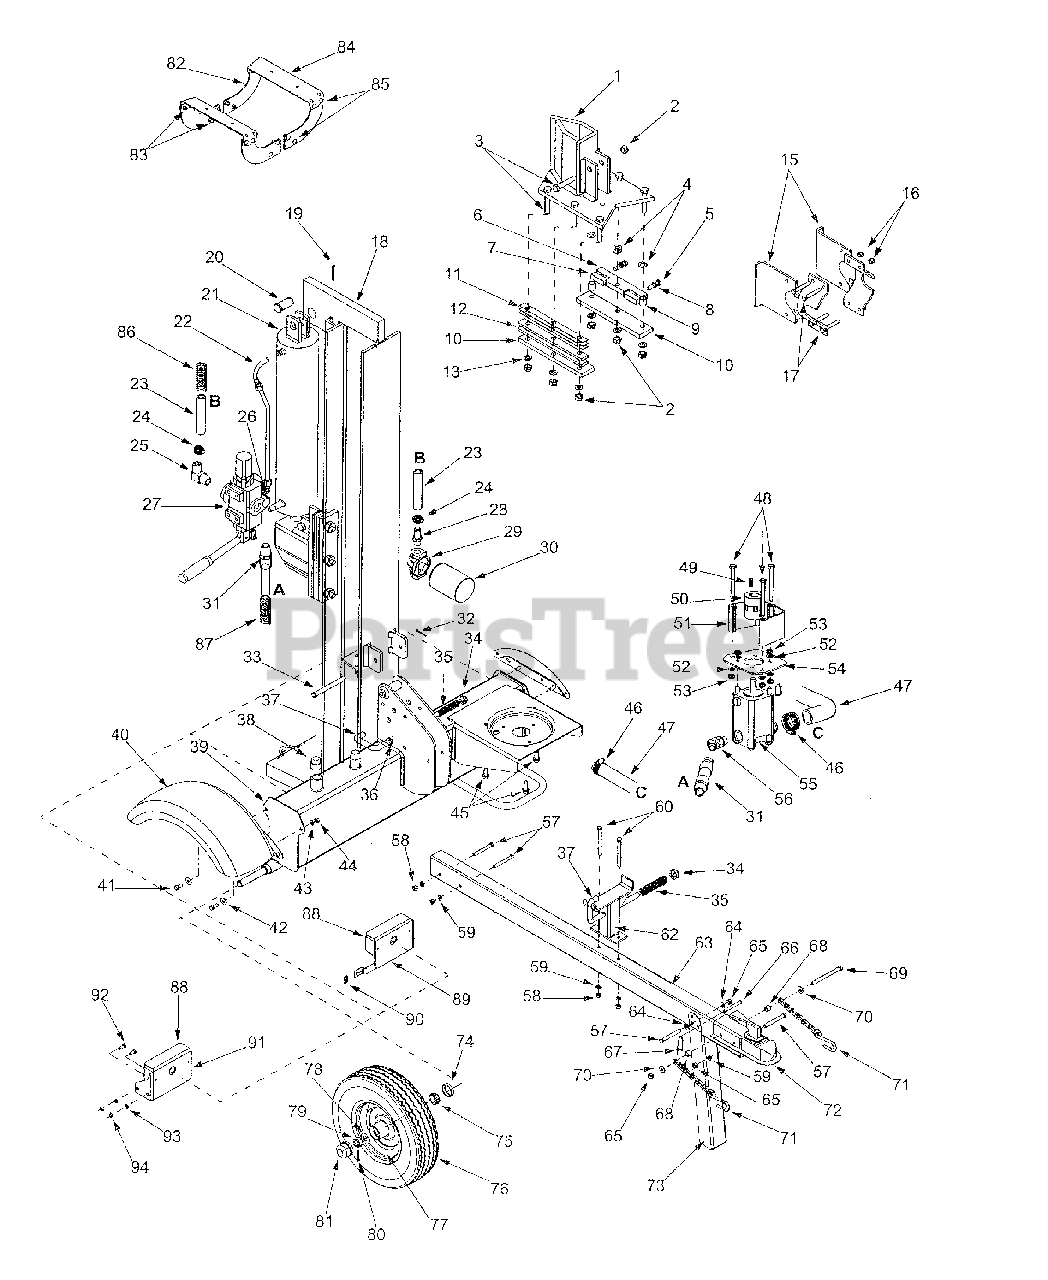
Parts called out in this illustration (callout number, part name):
2	Lock Nut 1/2-20
3	Hex Cap Screw 1/2-20 x 2.75
4	Flat Washer .531 ID x .93 OD
5	Hex Cap Screw 3/8-24 x 1.5
7	Adjustable Gib
8	Hex Jam Nut 3/8-24
9	Spacer
13	Lock Washer 1/2
13	Lock Nut 1/2-20
17	Hex Cap Screw 3/8-16 x 2.5
20	Clevis Pin
22	Hydraulic Tube
23	Return Hose 3/4" ID x 44" Lg.
24	Hose Clamp 5/8"
25	Return Elbow
26	90 Degree Solid Adapter
28	3/4" Hose Adapter
29	Filter Housing
30	Oil Filter
31	High Pressure Hydraulic Hose
32	Cotter Pin
33	Hinge Pin 1/2 x 4.8"
35	Compression Spring 4"
36	Flat Washer .635 ID x .93 OD
37	Locking Rod
38	Pipe Plug
39	Frame Assembly 4.0 Gal
42	Washer 5/16
43	Lock Washer 5/16
44	Hex Nut 5/16-24
45	Hex Washer Screw 3/8-16 x 1.
46	Hose Clamp
47	Suction Hose
48	Hex Screw 5/16-24 x 3.25
49	Square Key 3/16" x .75
50	Flexible Coupling (Stamped L075) .750 x .500 ID
50	Flexible Coupling (Stamped L075) .875 x .500 ID
50	Flexible Coupling (Stamped L075) .875 x .437 ID
51	Coupling Shield
52	Lock Washer 5/16" ID
53	Hex Nut 5/16-24
55	Gear Pump (11 gpm)
55	Gear Pump (9.5 gpm)
56	45 Degree Elbow
57	Hex Bolt 3/8-16 x 3"
58	Hex Nut 3/8-16
59	L-Washer 3/8"
60	Hex Bolt 3/8-16 x 4"
64	Flat Washer 3/8
65	Hex Lock Nut 3/8-16
66	Clovis Pin 5/16 x 2.5"
67	Spring Pin
68	Spacer 3/8" ID x .625" OD
69	Hex Bolt 3/8-16 x 4"
70	Flat Washer 3/8" ID x .87" OD
71	Chain
72	Hitch Coupler
75	Bearing Cone
76	Wheel Assembly
77	Rim Assembly
78	Flat Washer .76" ID x 1.5" OD
79	Slotted Nut 3/4-16
80	Cotter Pin 5/32" x 1-1/4"
85	Carriage Bolt 3/8-16 x 1.0
86	Hose Guard
87	Hose Guard
88	Taillight Assembly
93	Lock Washer 5/16
94	Hex Nut 5/16-24
